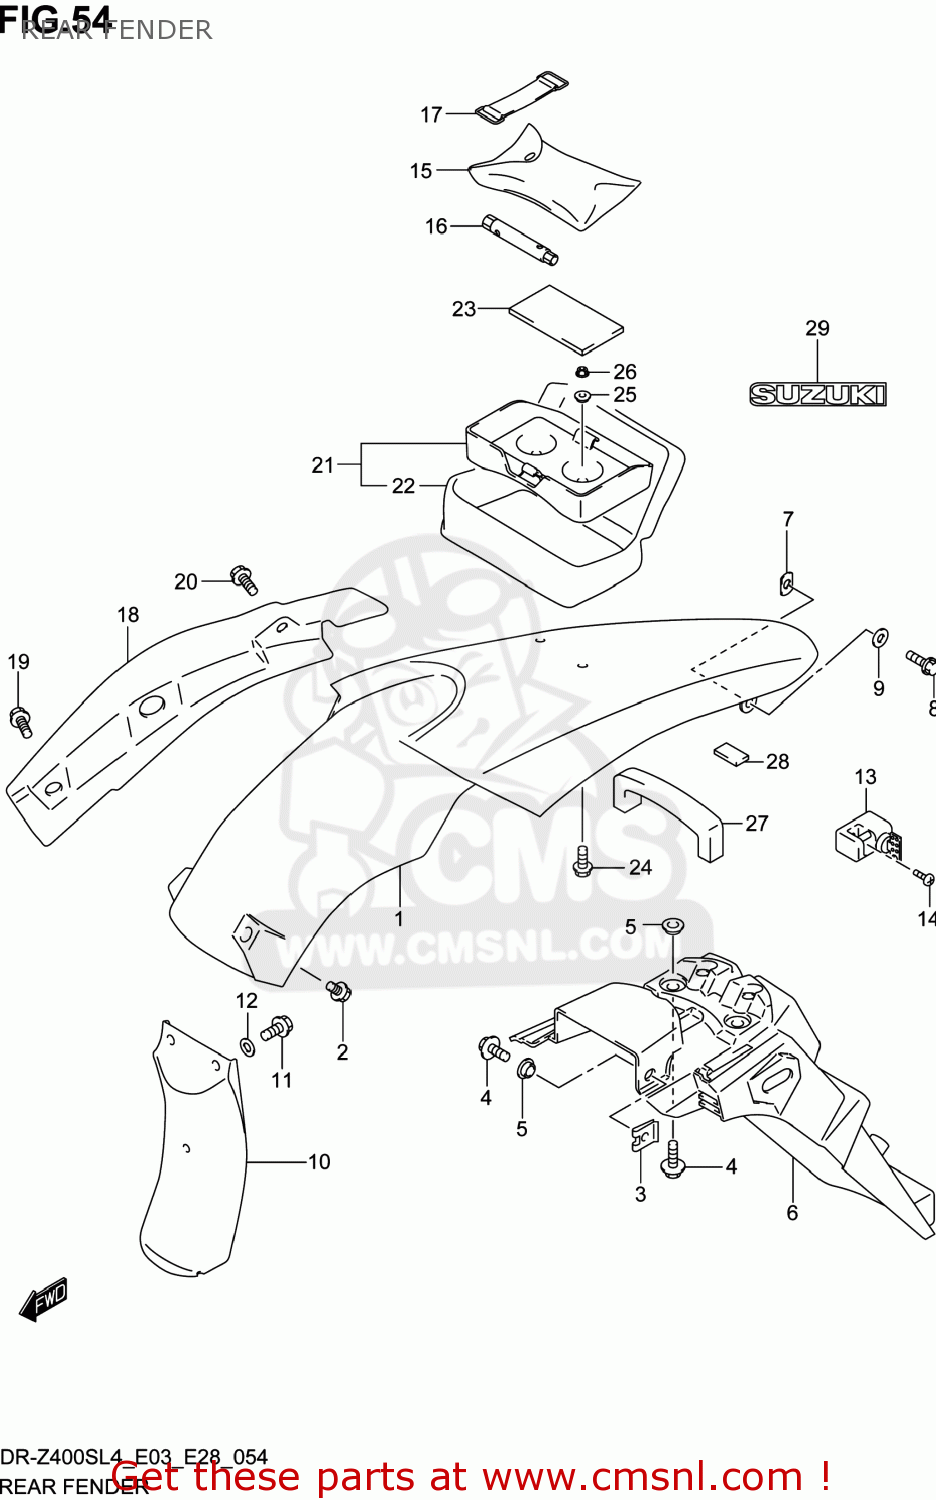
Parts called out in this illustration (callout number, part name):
1	FENDER,RR
2	BOLT(6X16)
3	PLATE,RR FENDER
4	BOLT(6X20)
5	WASHER
6	EXTENSION,RR FENDER
7	NUT,COWL
8	BOLT
9	WASHER
10	MUDGUARD,RR FENDER FR
11	BOLT
12	WASHER
13	LOCK SET,HELMET
14	SCREW(6X14)
15	TOOL ASSY
16	SPARK PLUG WRENCH(8X10)
17	BAND
18	MUDGUARD,RR FENDER,R
19	BOLT(6X18)
20	BOLT(6X12)
21	BAG ASSY,SEAT TAIL
22	BAG,SEAT TAIL
23	CUSHION,RR BAG
24	BOLT
25	WASHER
26	NUT
27	SEALER,SIDE COVER L
28	PROTECTOR(170X95X3.0)
29	EMBLEM,SUZUKI
